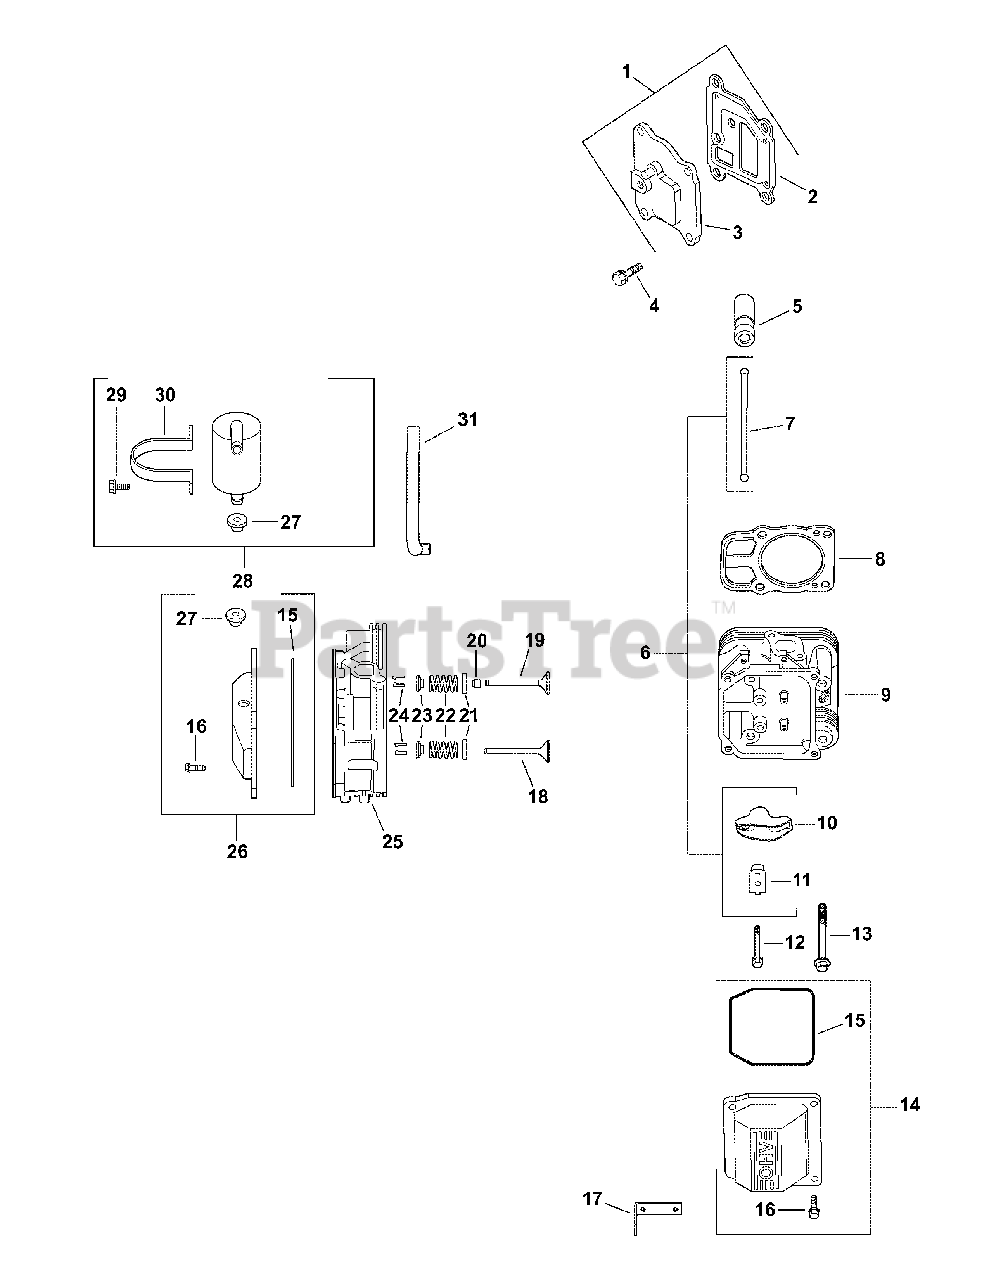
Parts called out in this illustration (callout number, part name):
1	KIT, BREATHER COVER W/GASKET
2	GASKET, BREATHER
3	COVER, BREATHER
4	SCREW, FLG THD FRM M6X1.0X20
5	KIT, HYDRAULIC VALVE LIFTER
6	KIT, VALVE TRAIN
8	KIT, GASKET CYLINDER HEAD
9	KIT, HEAD #2 (Includes KH-25-072-04-S)
11	PIVOT, ROCKER ARM
12	SCREW, FLG M6X1.0X34
13	SCREW, FLG M10X1.5X90
14	KIT, VALVE COVER-PLAIN
15	O-RING, VALVE COVER
16	SCREW, FLG M6X1.0X30
17	STRAP, LIFTING
18	VALVE, EXHAUST (STD)
18	VALVE, EXHAUST (.25)
19	VALVE, INTAKE (STD)
19	VALVE, INTAKE (.25)
20	SEAL, VALVE STEM
21	RETAINER, SPRING
22	SPRING, VALVE
23	CAP, VALVE SPRING
24	KIT, RETAINER
25	KIT, HEAD #1
26	KIT, VALVE COVER BREATHER
27	GROMMET, RUBBER
28	KIT, BREATHER SEPERATOR
29	SCREW, FLG M6X1.0X16
30	STRAP, BREATHER
31	HOSE BREATHER
